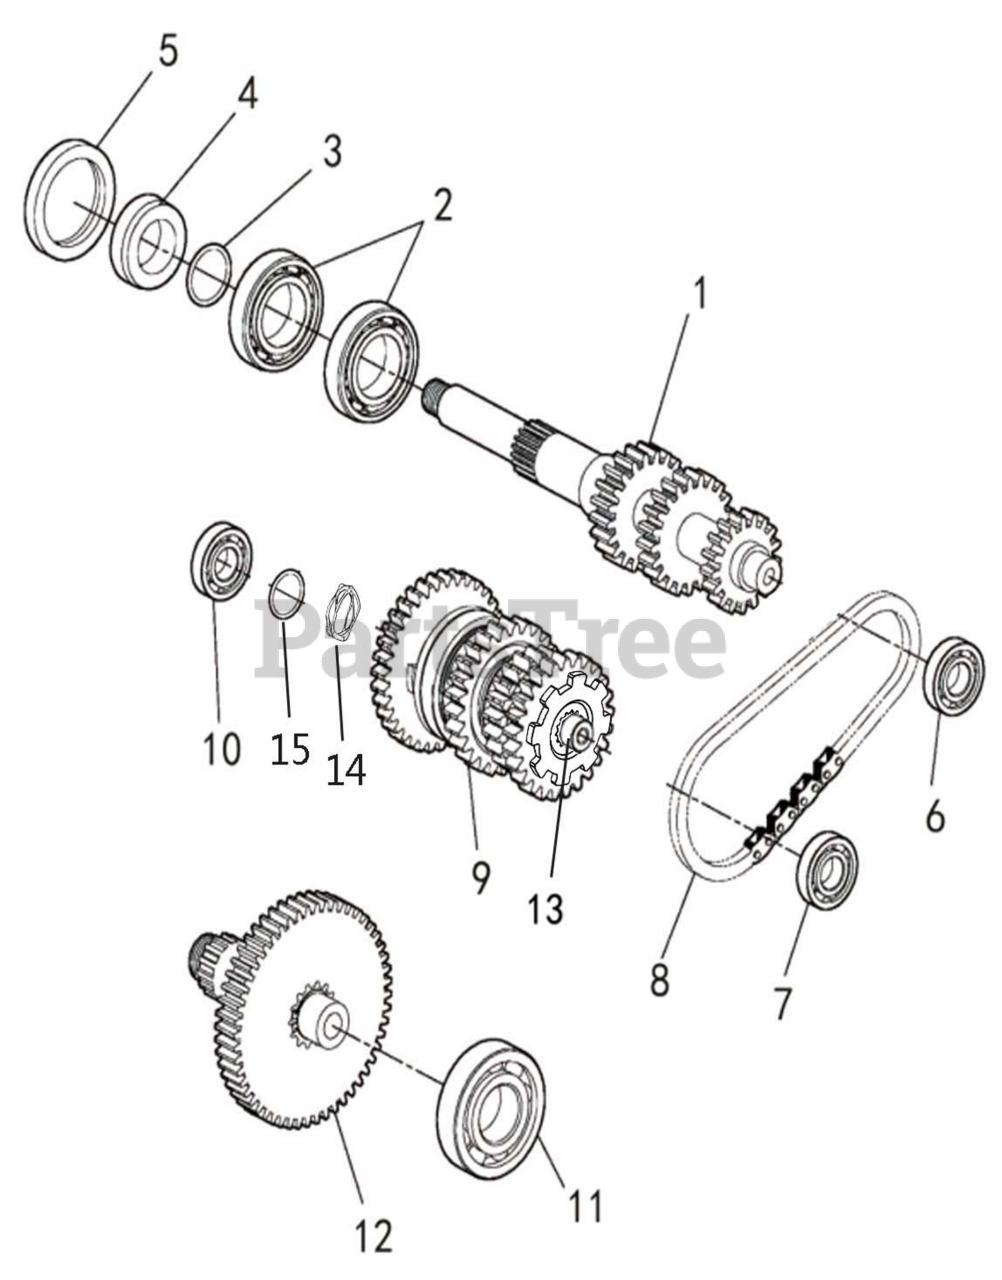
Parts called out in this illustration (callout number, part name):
1	TRANSMISSION MAIN SHAFT
2	BEARING 6006C3
3	O-RING 26.1X2.4
4	SECONDARY CVT BUSHING
5	OIL SEAL 42X55X8
6	BEARING 6203
7	BEARING 6202
8	TOOTH SHAPED CHAIN FOR R GEAR
9	COUNTER SHAFT 750cc
10	BEARING 6203DLA8
11	BEARING 6303
12	X DRIVESHAFT ASSEMBLY
13	COUNTER SHAFT
14	WAVE WASHER
15	WASHER 23 x 31 x 0.6
